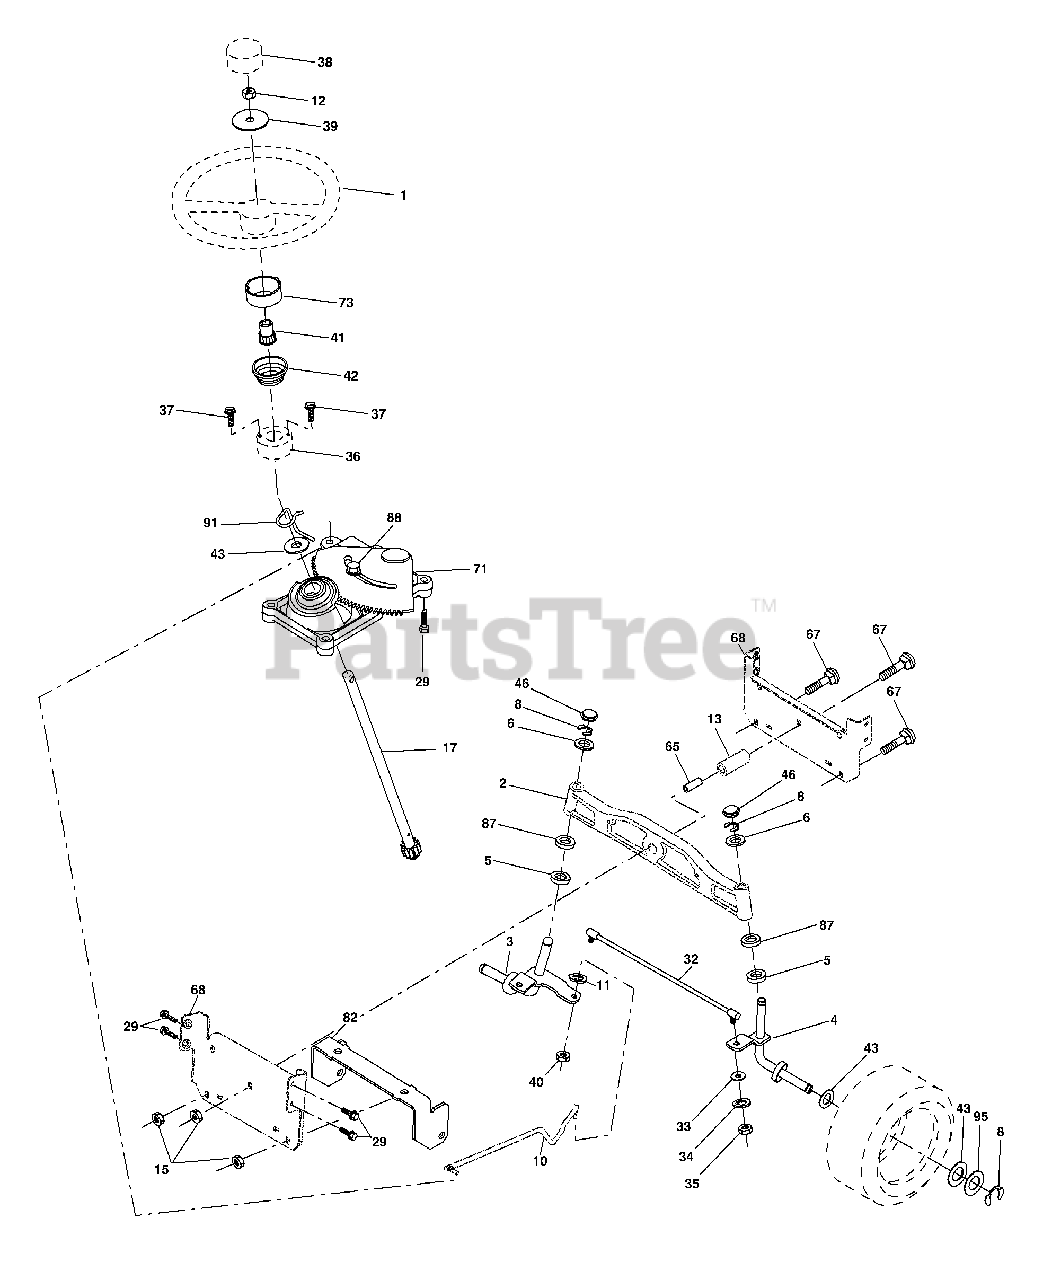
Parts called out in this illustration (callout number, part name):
1	Wheel Steering
2	Axle Asm
3	Spindle Asm LH
4	Spindle Asm RH
5	Bearing Race Thrust Harden
6	Washer 25/32 x 1-5/8 x 16 Ga.
8	Ring Klip #t5304-75
10	Link Drag
11	Washer Lock Hvy Hlcl Spr 3/8
12	Nut Hex Jam Toplock 1/2-20 unf
13	Spacer Bearing Axle Front
15	Nut Hex Flange Lock
17	Shaft Asm. Steering
29	Screw 3/8-16 x 3/4
32	Rod Tie
33	Washer 11/32 x 3/4 x 16 Ga.
34	Washer Lock Hlcl Spr 5/16
35	Crownlock Nut 5/16-24 unf
36	Bushing Strg
37	Screw
38	Insert Cap Strg Wh
39	Washer 9/16 ID x 1-1/2 OD 11Ga.
40	Nut Crownlock 3/8-24
41	Adaptor Wheel Strg
42	Boot Steering
43	Washer 25/32 1 1/4 x 16 Ga.
46	Cap Spindle
65	Spacer Brace Axle
67	Bolt, Rdhd Sq 3/8-16 unc x 2-1/4
68	Axle, Brace
71	Steering Asm.
73	Extension Steering Stealth
82	Bracket Susp. Chassis Front
87	Washer Flat .781 x 1-1/2 x .15
88	Bolt Shoulder 7/16-20 unc
91	Clip Steering
95	Washer Harden .793 x 1.637 x .060
